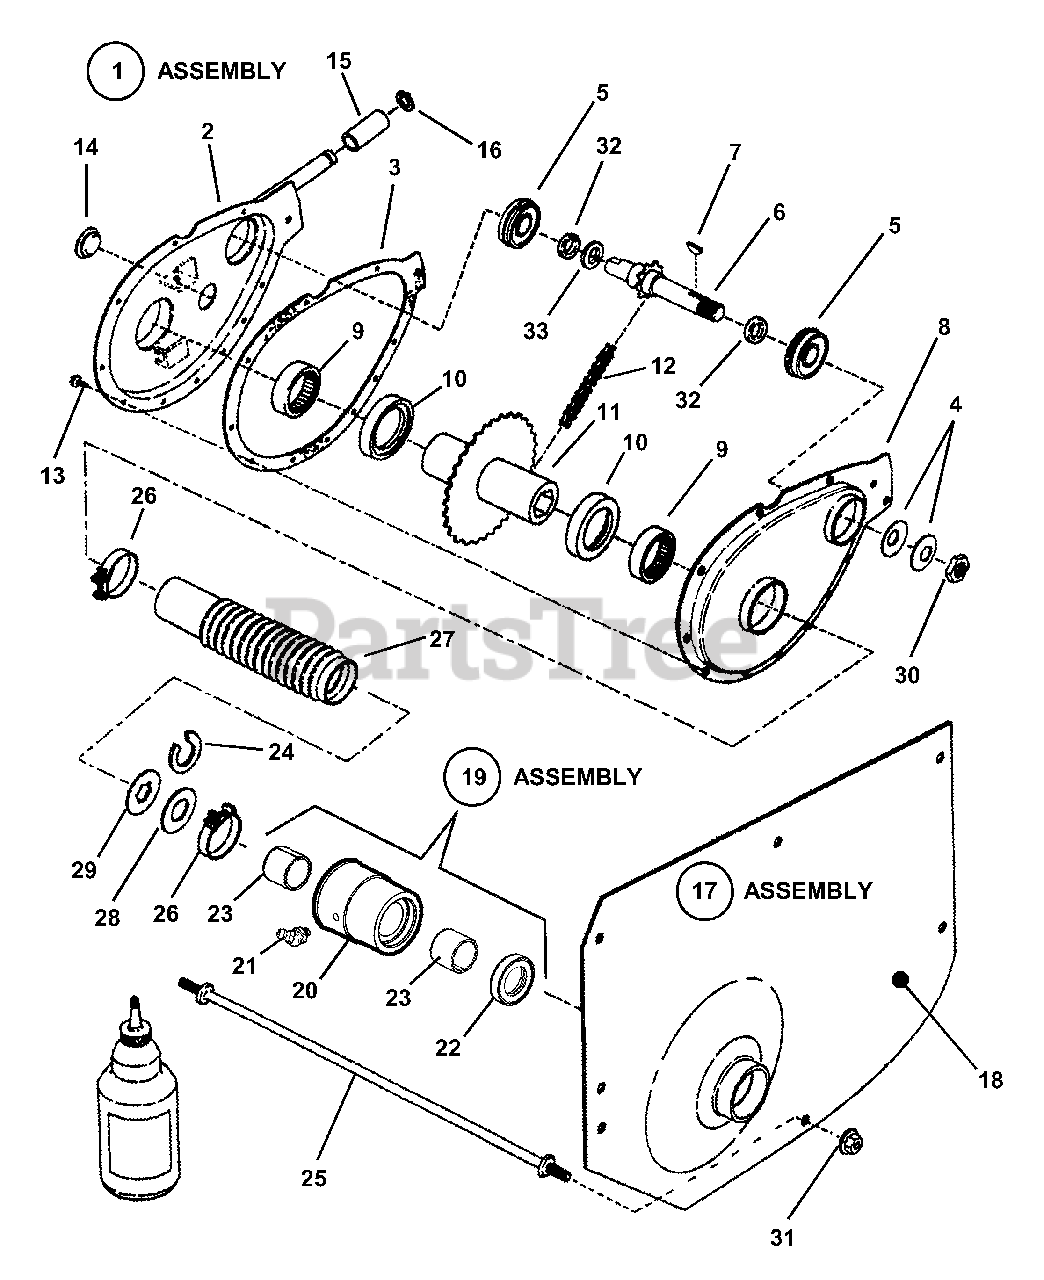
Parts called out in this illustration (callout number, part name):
1	ASSEMBLY, Chain Case
2	CASE, Sprocket (Weldment)
3	GASKET, Case Cover
4	WASHER, Belleville
5	BEARING, Ball
6	SPROCKET & SHAFT
7	KEY, 1/8 x 5/8" Woodruff
8	COVER, Chain Case
9	BEARING, Needle
10	WASHER, Nylon Thrust
11	HUB & SPROCKET (Weldment)
12	CHAIN
13	SCREW, #10-24 x 1/2" Hex Washer Self-Tap (Torx)
14	PLUG, Oil Fill & Check
15	ROLLER
16	RING, 1/2" External Retaining
17	ASSEMBLY, Left Hand Fender
18	FENDER, Left Hand
19	ASSEMBLY, Axle Bearing
20	BEARING, Left Hand Fender
21	FITTING, Lube
22	SEAL, Dust/Grease Axle
23	BEARING, 3/4" I.D. DX
24	WASHER, Shim
25	ROD, Cross-Tie
26	CLAMP, Boot
27	BOOT, Oil Seal
28	WASHER, Thrust Nylon
29	WASHER, Thrust
30	NUT, 5/8-18 Hex Nyloc
31	NUT, 5/16-24 Hex Flange Lock
32	O-RING
33	WASHER, Wave
